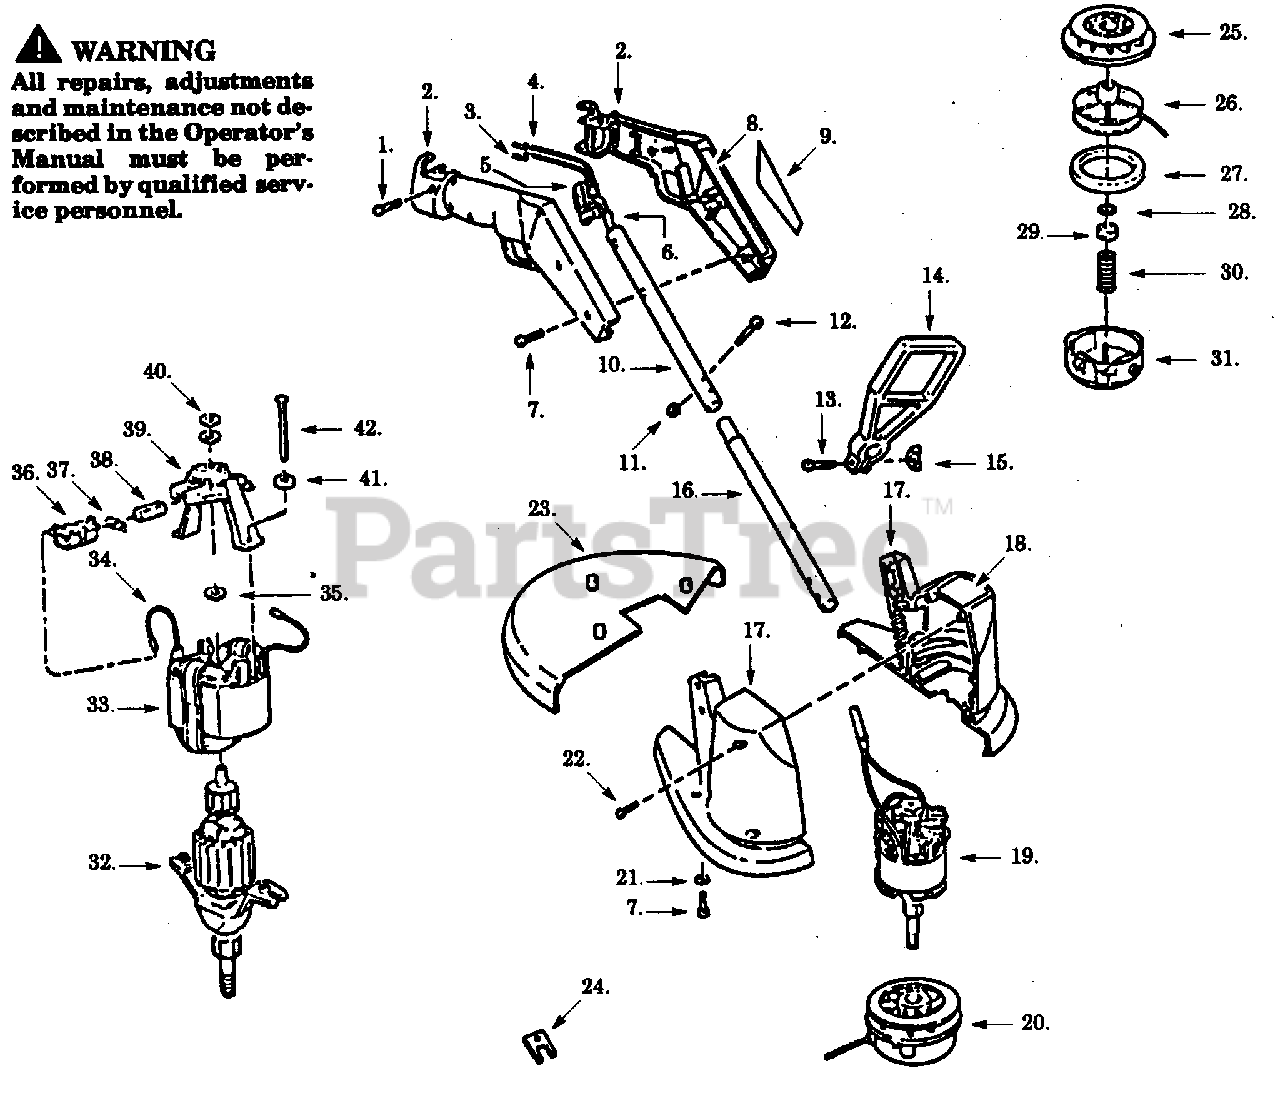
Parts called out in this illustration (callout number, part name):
2	Handle Set
3	Wire Terminal Ass'y.
4	Wire Terminal Ass'y.
5	Trigger Switch
6	Harness Ass'y.
8	Handle Label
9	Warning Label (Not a serviceable part)
10	Upper Tube
11	Stop Nut
14	Assist Handle
15	Wing Nut
16	Lower Tube
17	Housing Set
18	Housing Top Label
19	Motor Ass'y.
20	Cutting Head Ass'y.
23	Guard & Blade Ass'y.
25	Rear Plate/Baffle Ass'y
26	Spool & Line
27	Foam Pad
29	Adapter Nut
31	Hub Ass'y.
32	Armature Endbell
33	Field Ass'y.
34	Lead Wire Ass'y.
36	Brush Holder Ass'y.
37	Brush Spring
39	Endbell Ass'y. (Brush)
40	Retaining Ring
41	Lockwasher
